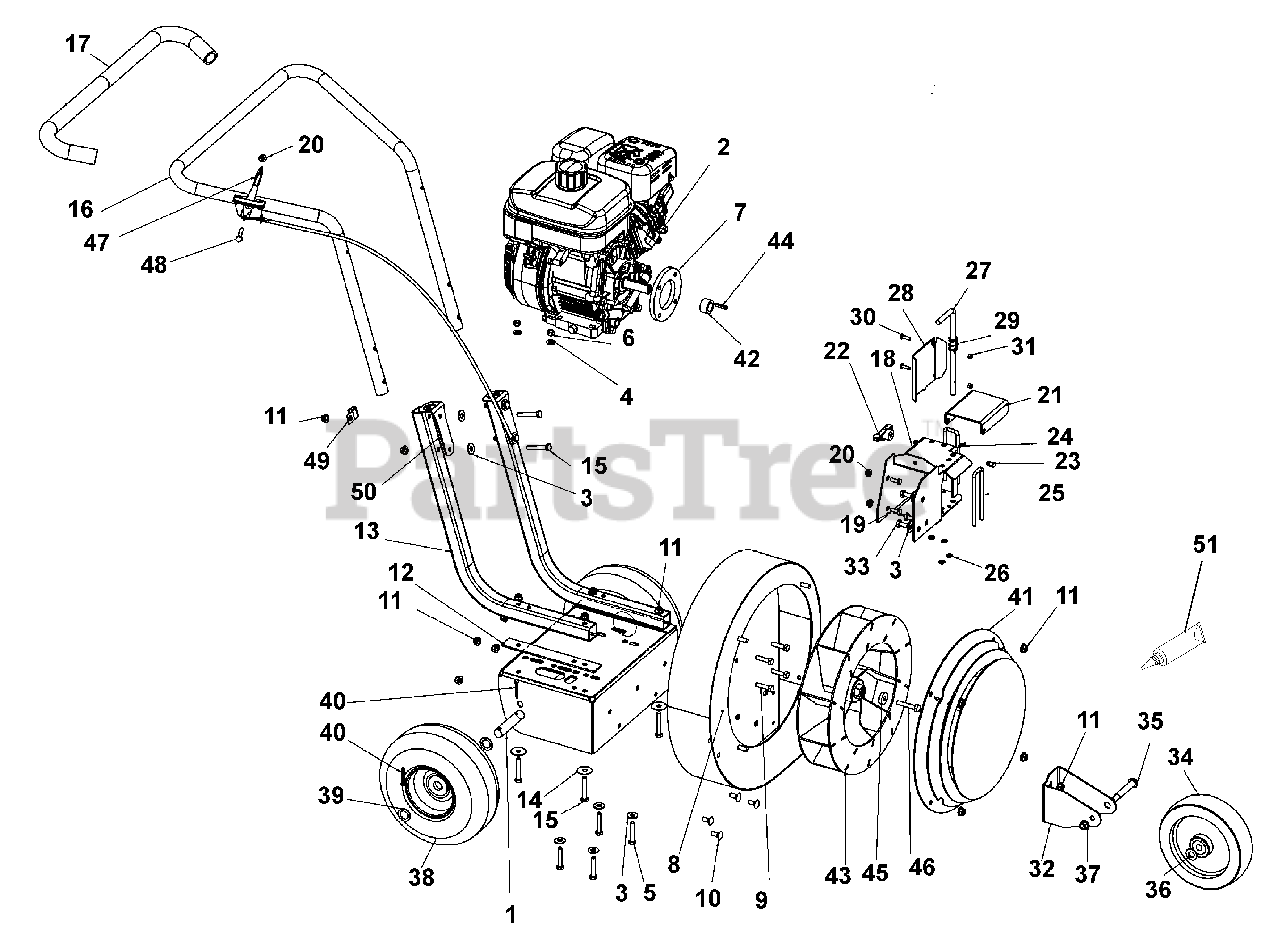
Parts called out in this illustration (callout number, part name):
1	WMT-BLOWER FRAME, SM
2	ENGINE,SUBARU 6HP SP170 (CARB)
3	@WSHR-FL-STL.38X.875X.083 YWZC
4	@WSHR-FL-STL.344X.688X.065YWZC
5	@BLT-HEX .31-18X1.75 GR5 YWZC
6	@NUT-HEX .31-18 YWZC
7	SPACER-ENGINE
8	WMT-BLOWER HOUSING SM
9	@BLT-HEX .31-24X1.25 GR5 YWZC
10	@BLT-RDHDSQNK .31-18X.75 G5YZ
11	@NUT-LK-NYL-FLG .31-18 YWZC
12	SPACER-RUBBER
13	TUBE-HANDLEBAR, LOWER SQ
14	WSHR-FL-STL .347X1.254X.048YWZ
15	@BLT-HEX .31-18X2.00 GR5 YWZC
16	TUBE-HANDLEBAR, UPPER
17	GRIP-HANDLEBAR, UPPER
18	WMT-OUTLET CHUTE
19	@BLT-HEX .25-20X.75 GR5 YWZC
20	@NUT-LK-NYL-FLG .25-20 YWZC
21	BRKT-OUTLET DOOR
22	KNOB,WING .31-18 UNC NYL/TALC
23	PIN-CLEV .313X.500 YWZC
24	PIN-HAIR, ENDRIES #25 YWZC
25	WIREFORM-GUARD, SAFETY
26	NUT-PUSH .25X.50 O.D.
27	WIREFORM-LEVER, DIRECTION
28	BRKT-FLAP, DIRECTION
29	SPRING-COMP 1.0LX.72 OD .05DIA
30	@SCR-MCH 10-24X.75 HWH YWZC
31	@NUT-LK-NYL 10-24 W/INSRT YWZC
32	BRKT-WHEEL, FRONT
33	@BLT-HEX .31-18X.75 GR5 YWZC
34	WHEEL 8X2 W/.5 BORE BLK
35	BLT-SHLDR .38-16X2.50 HWH G5
36	WSHR-FL-NYL .518X1.000X.080
37	@NUT-LK-TOP-FLG .38-16 YWZC
38	WHEEL-10X3.75 PNEU. WHITE
39	WSHR-FL-STL.754X1.125X.062YWZC
40	@PIN-CTR .16X1.25 EXTPRSQCT YZ
41	WMT-INLET GUARD SM
42	BUSHING, SLEEVE .76X1.13X.650
43	WMT-FAN, BLOWER SM
44	KEY-SQ .188X1.0X.188 SAE 8630
45	WSHR-FL-STL .350X1.00X.250 YWZ
46	BLT-HEX .31-24X2.00 G8 YZ EP80
47	THROTTLE CONTROL
48	@BLT-HEX .25-20X2.00 GR5 YWZC
49	J-CLAMP
50	BRKT-HANDLEBAR MOUNT
51	ADHESIVE-LOCTITE 609 .5ML
